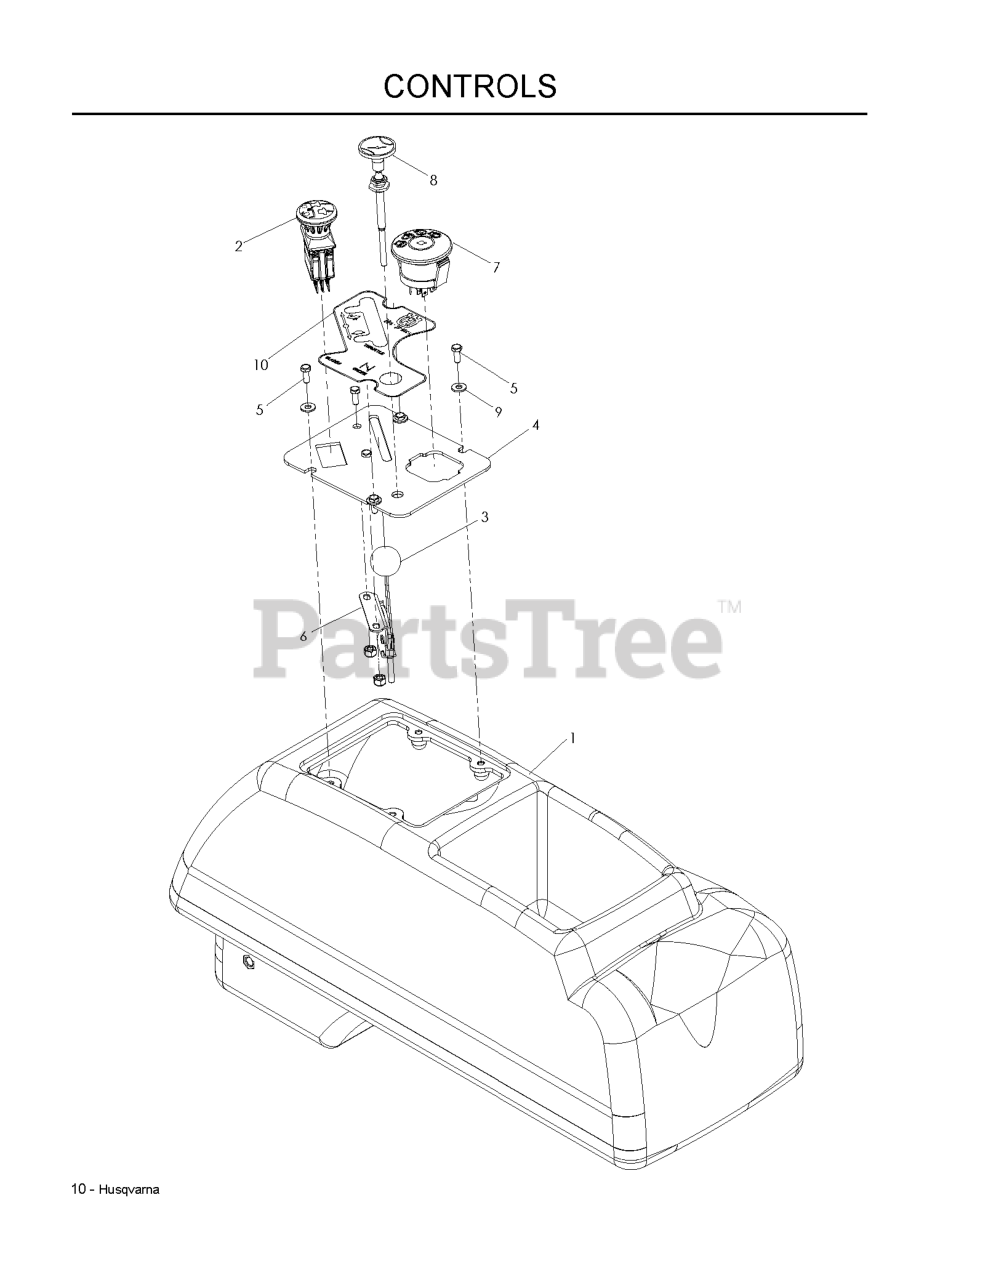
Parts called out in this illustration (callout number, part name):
1	FENDER CONSOLE
2	RP SWITCH.PTO.TERMINAL.STD.RED
3	THROTTLE CABLE
4	CONSOLE PLATE, BLACK
5	HCS #10-24 X 1/2
6	NUT 10-24 NYLOC
7	RP IGNITION SWITCH
8	CHOKE CONTROL
9	WASHER #10
10	DECAL, CONSOLE
